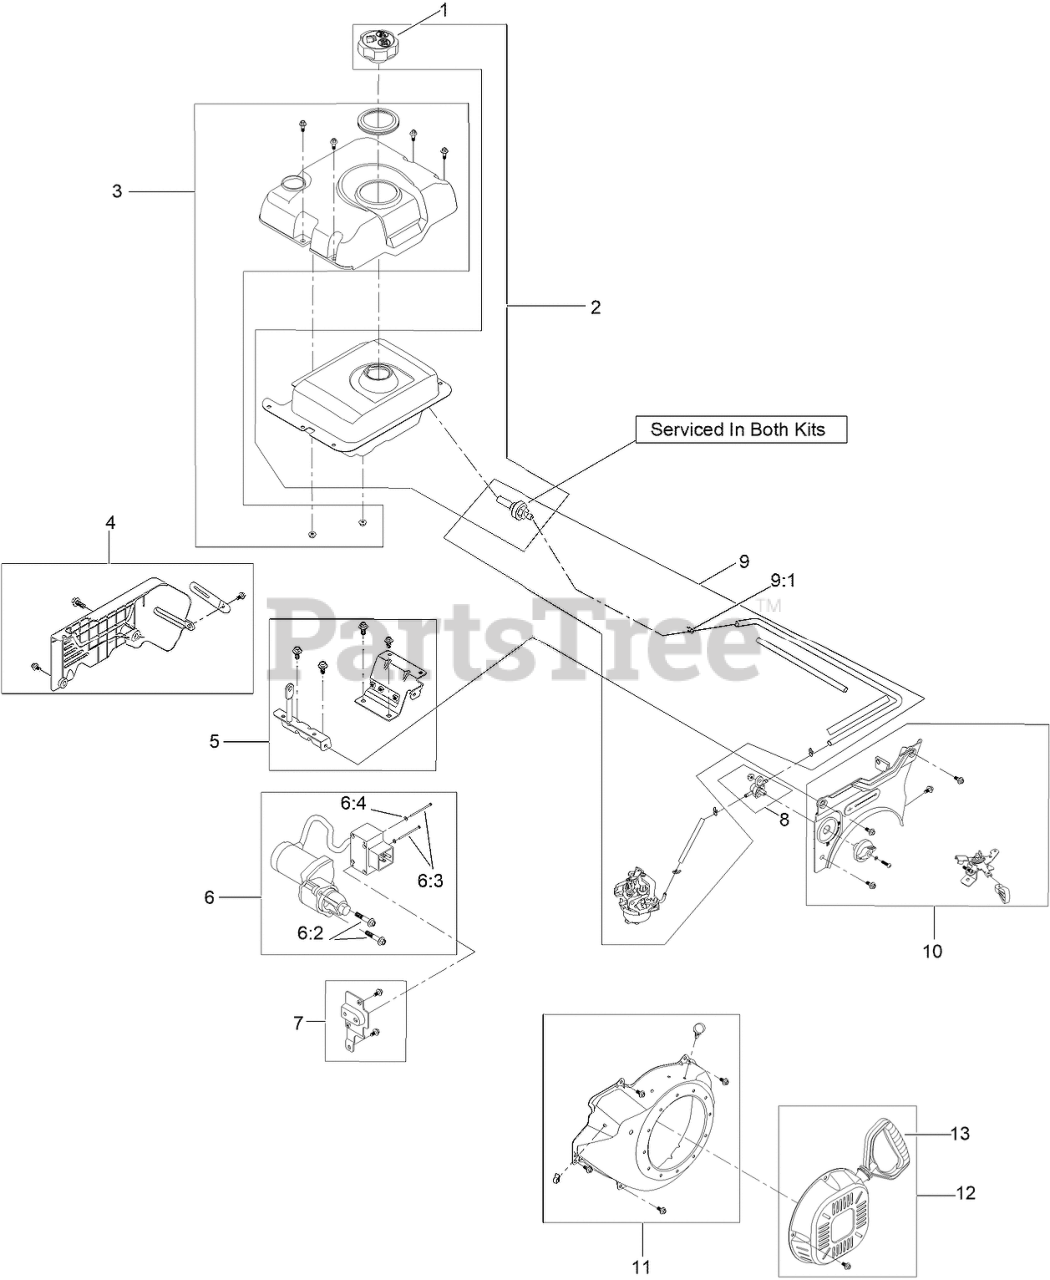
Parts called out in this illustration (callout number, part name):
1	CAP-FUEL
2	FUEL TANK AND CAP KIT
3	FUEL TANK COVER KIT
4	REAR PANEL AND HARDWARE KIT
5	TANK MOUNT BRACKET KIT
6	ELECTRIC STARTER KIT
6:2	SCREW-HHF
6:3	SCREW-BHP
6:4	WASHER-PLAIN
7	SWITCH BOX BRACKET KIT
8	FUEL SHUT-OFF VALVE KIT
9	FUEL LINE KIT
9:1	CLAMP-HOSE
10	FRONT PANEL KIT
11	RECOIL SHROUD KIT
12	RECOIL KIT
13	HANDLE-RECOIL
